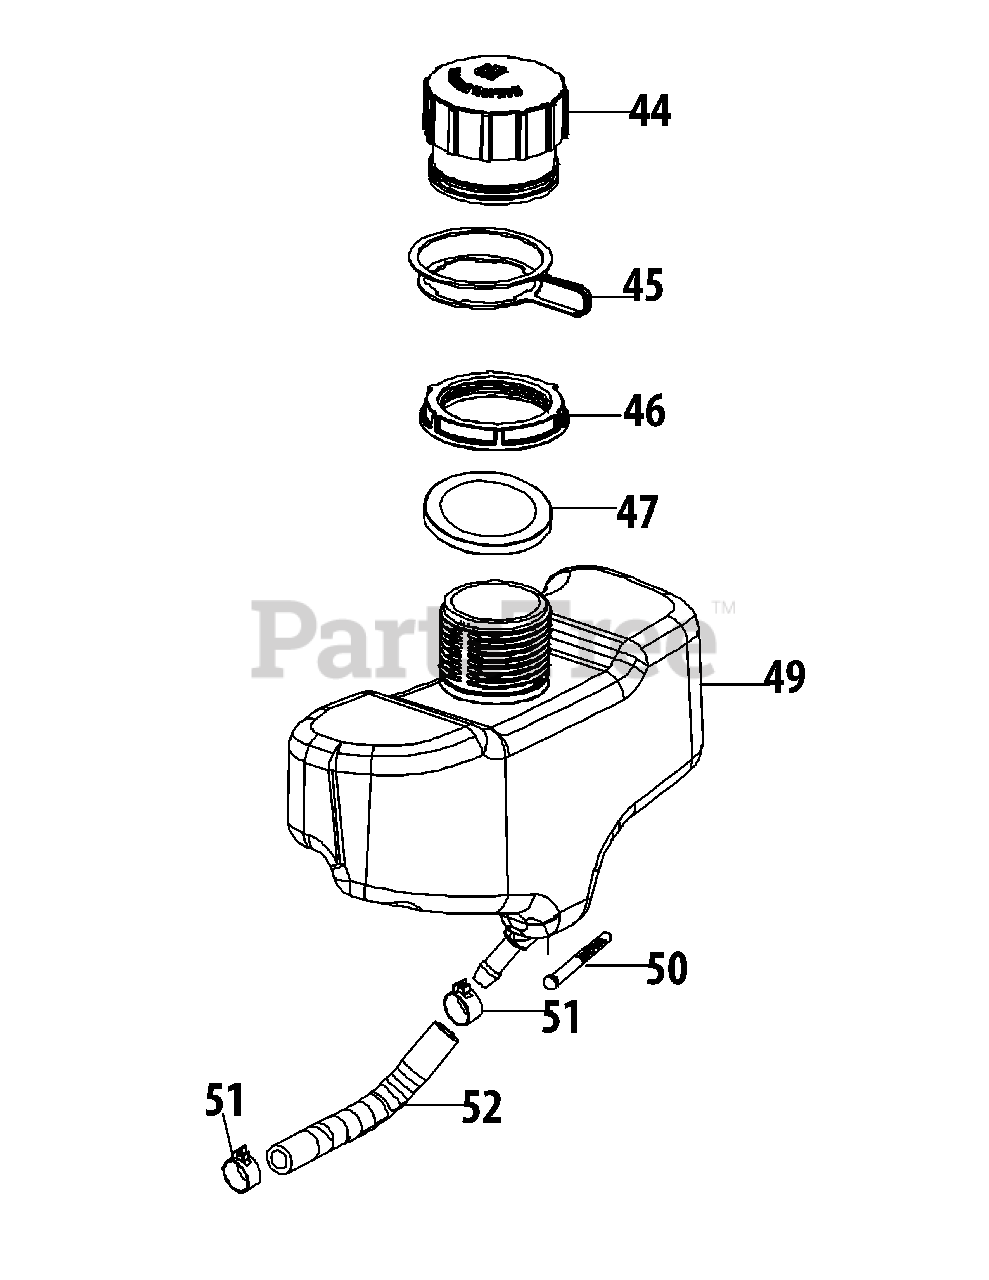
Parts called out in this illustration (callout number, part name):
44	Fuel Cap Assembly
45	Fuel Cap Tether
46	Fuel Tank Nut
47	Fuel Tank Upper Grommet
49	Fuel Tank
50	Fuel Filter
51	Fuel Hose Clamp
52	Fuel Hose
